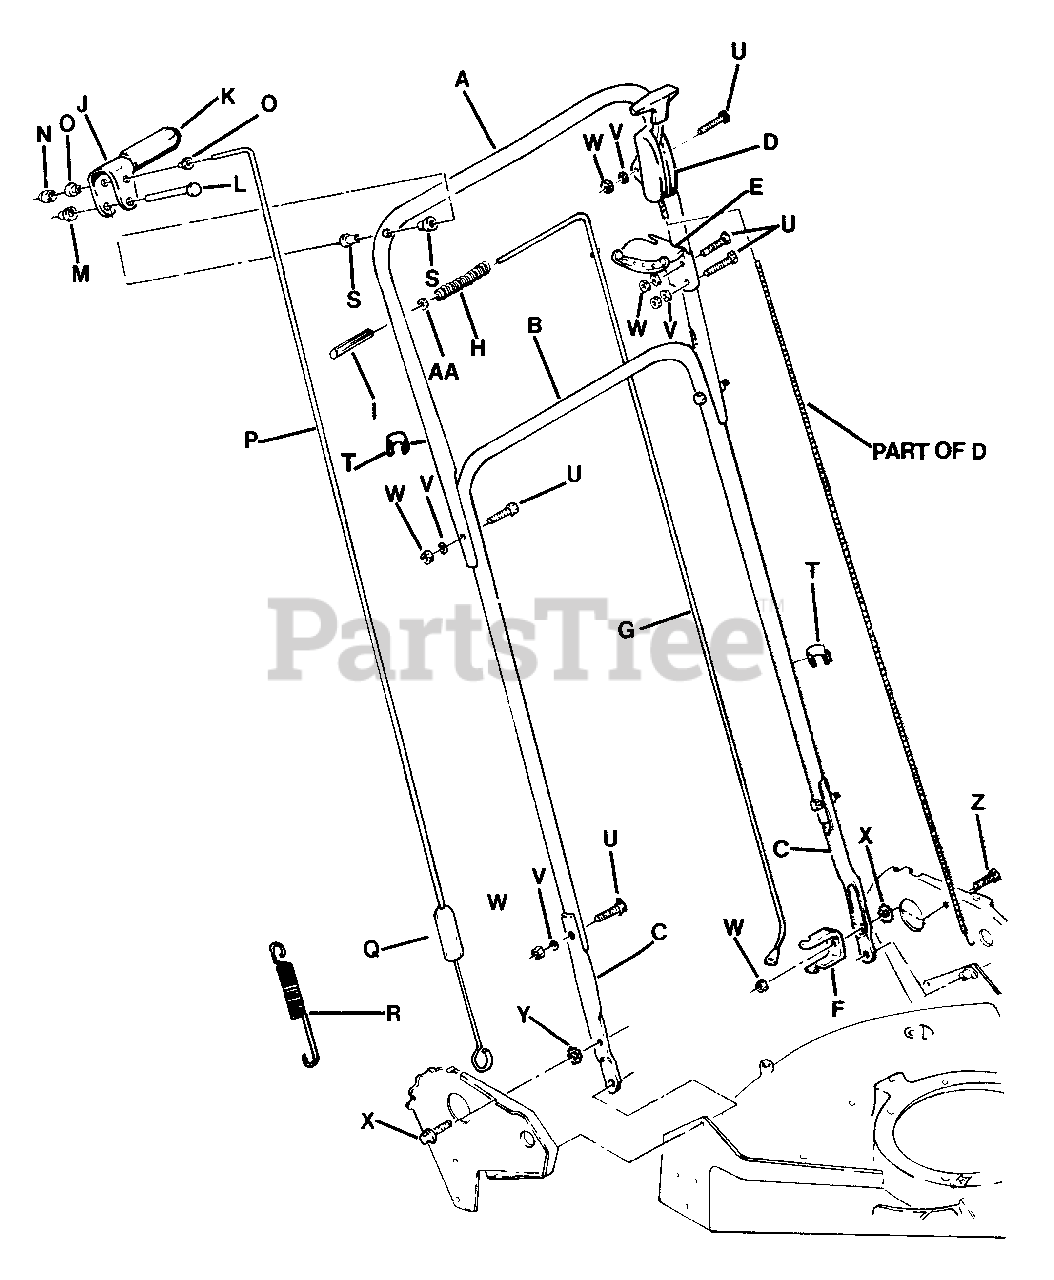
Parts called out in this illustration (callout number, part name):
A	HANDLE, Upper
B	HANDLE, Pivoting
C	HANDLE, Lower
D	CONTROL, Throttle (Briggs)
E	SECTOR, Speed Control
F	ANCHOR, Speed Control
G	LEVER, Speed Control
H	SPRING, Speed Control Lever
I	GRIP, Speed Control Lever
J	HANDLE, Clutch
K	GRIP, Clutch Handle
L	PIN, Clutch Handle
M	NUT, 1/4" Push
N	NUT, 1/8" Push
O	BUSHING, Pull Rod (Nylon)
P	ROD, Clutch Pull
Q	COVER, Vinyl
R	SPRING, Clutch
S	BUSHING, Clutch Handle Pin
U	SCREW, 1/4-28 x 1-3/8" Hex Head Cap, Grade 5
V	WASHER, 1/4" Internal Tooth Lock
W	NUT, 1/4-28 Hex
X	SCREW, 5/16-24 x 1-1/4" Hex Head Cap, Grade 2
Y	WASHER, 5/16" Internal/External Tooth
Z	SCREW, 5/16-24 x 1" Hex Head Cap, Grade 5
AA	WASHER, 5/16" SAE Flat
